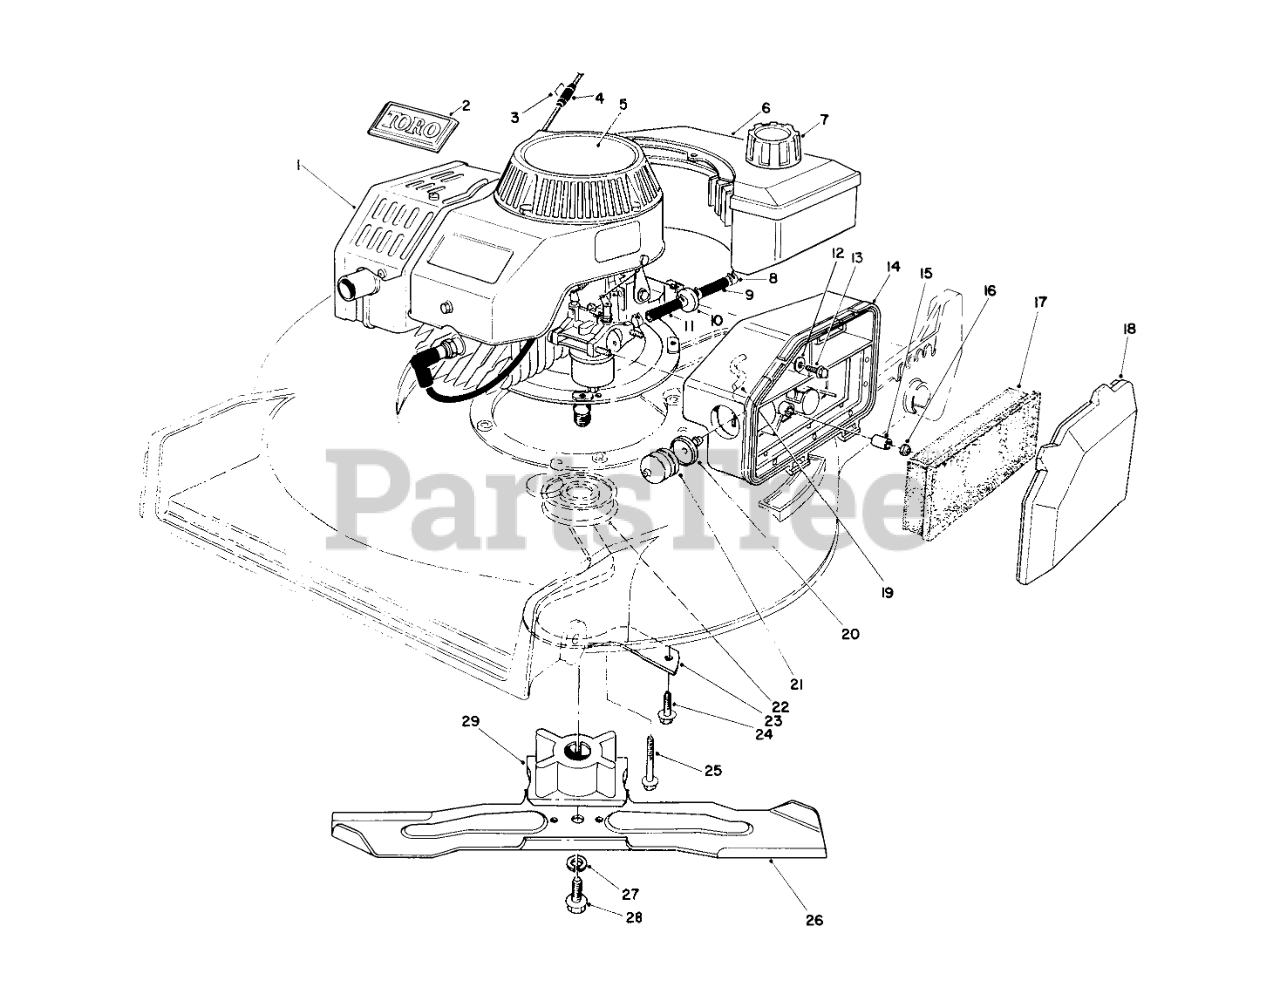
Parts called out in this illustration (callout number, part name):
1	Engine
2	TORO LOGO PLT
3	Staple
5	DECAL - 2 CYC RECOIL
6	Gas Tank Assembly
7	GAS CAP ASM
8	CLAMP-FUEL LINE
9	HOSE-FUEL
10	FILTER-FUEL
11	HOSE-FUEL
12	WASHER-FLAT
13	SCREW-HH
14	BODY-AIR CLEANER
15	SPACER
17	ELEMENT-AIR CLEANER
18	COVER-AIR CLEANER
19	HOSE-PRIMER
20	BODY-PRIMER
21	BULB-PRIMER
22	PULLEY-DRIVE, ZONE START
23	BELT GUIDE
24	SCREW-HWHTF
25	SCREW-HHF
26	BLADE-21in
27	WASHER-LOCK
28	SCREW-BLADE
29	BLADE RETAINER
